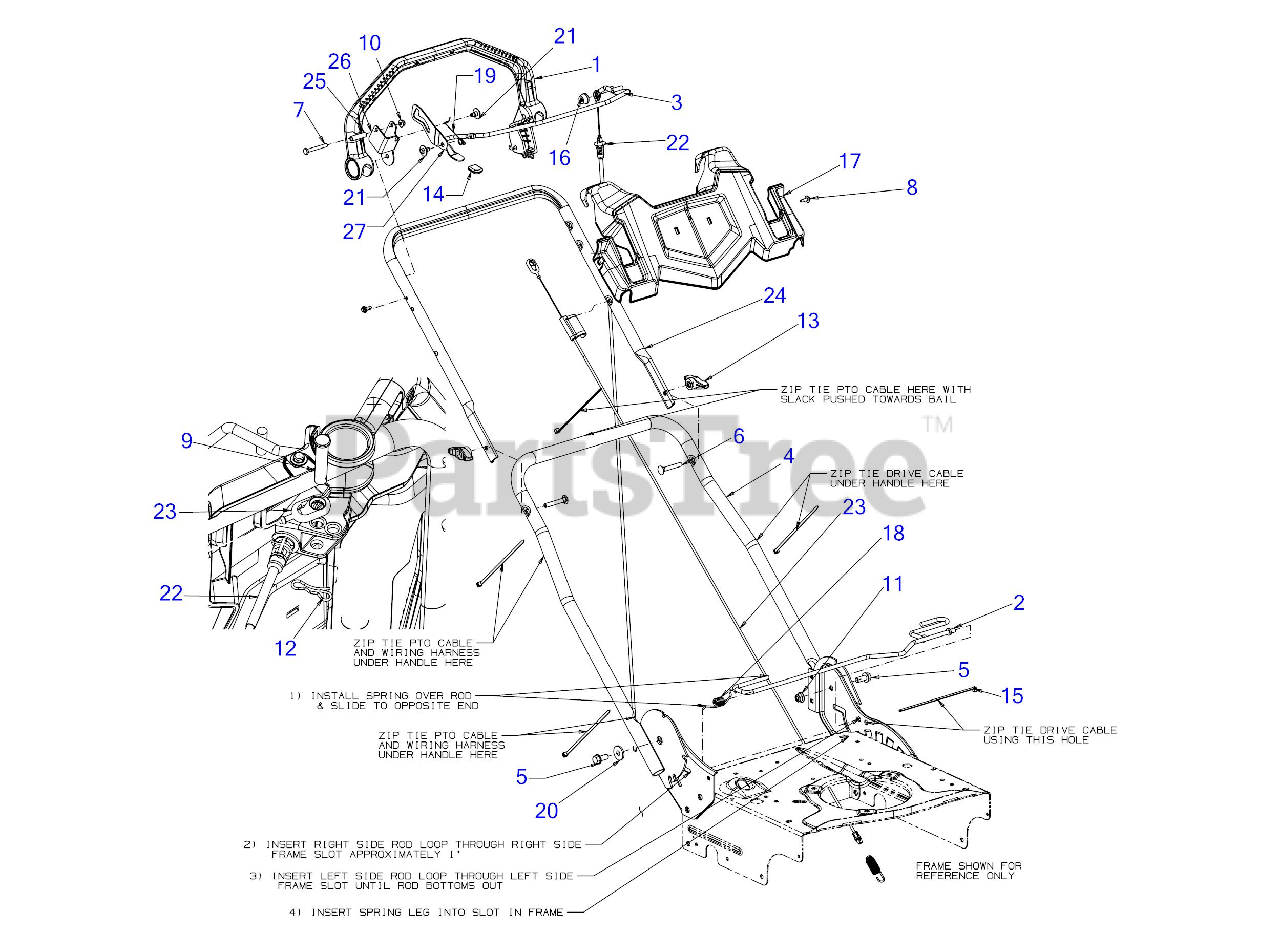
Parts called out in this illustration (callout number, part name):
1	DRIVE HANDLE ASSEMBLY (BLACK)
2	PIVOT HANDLE ROD
4	LOWER HANDLE ASSEMBLY
5	SCREW 3/8-16 x .875 GR5
6	CARRIAGE BOLT 5/16-18 x 2.00 GR5
7	SCREW 1/4-20 x 2 GR5
8	SCREW M6-1 x .625
9	CLEVIS PIN 3/8 x 1.87
10	FLANGE LOCK NUT
12	BOW TIE COTTER PIN 1/4-5/16
13	WING KNOB 5/16-18
15	7" CABLE TIE
16	PUSH CAP 0.3125
17	HANDLE CONSOLE
18	TORSION SPRING .48 x .177
19	TORSION SPRING
20	SHOULDER SPACER .625 x .169
21	SHOULDER SCREW
22	CONTROL CABLE
23	DRIVE CABLE
25	SPACER:.260 x .372 x 1.420
27	LOCK OUT BRACKET
